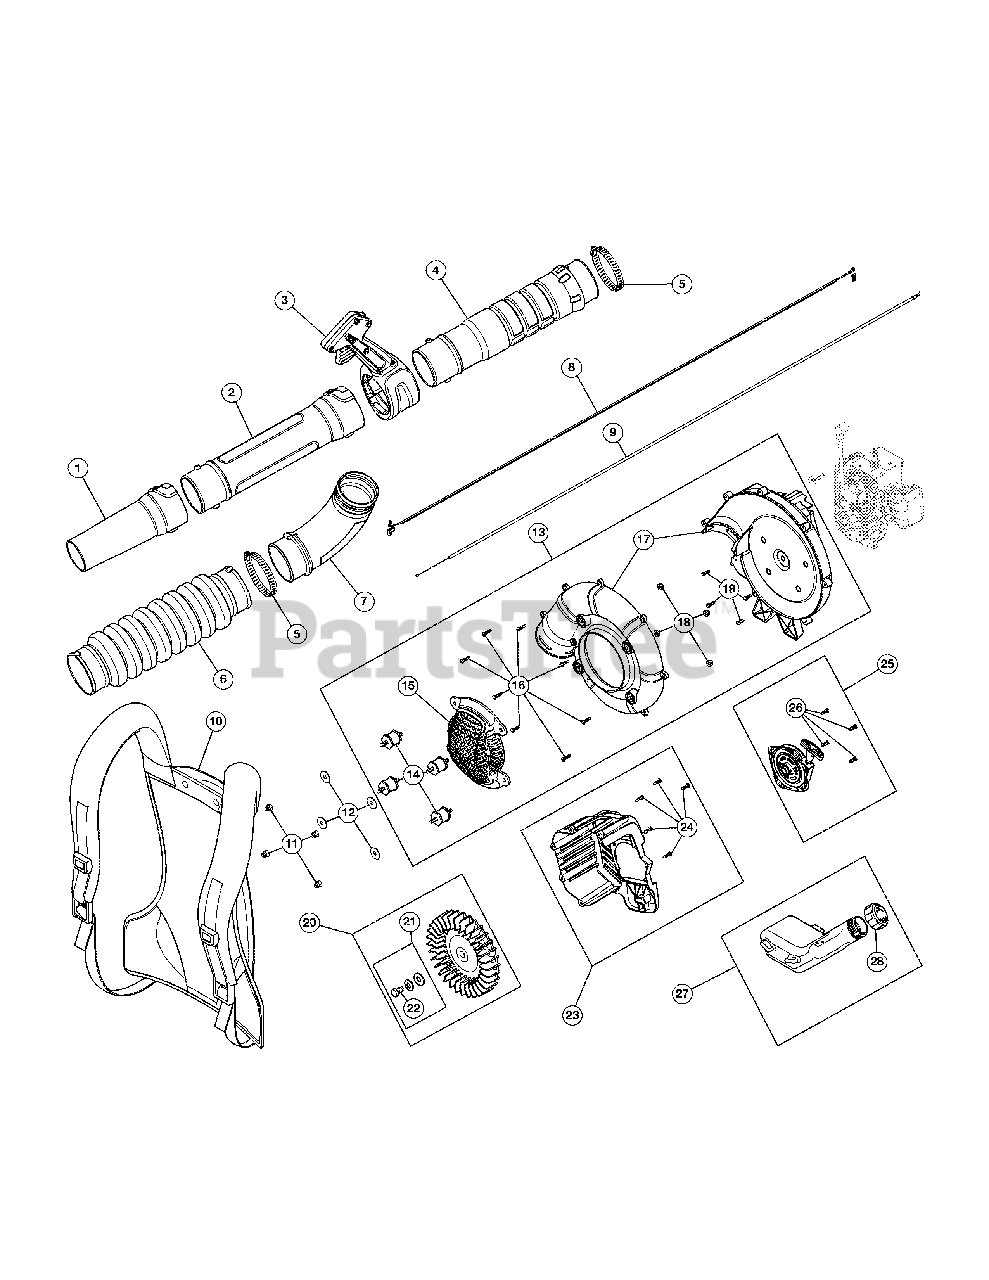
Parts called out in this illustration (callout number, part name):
1	Nozzle
2	Lower Blower Tube
3	Throttle Grip Assembly
4	Upper Blower Tube
6	Flex Tube
8	Lead Wire
9	Throttle Cable
10	Harness
11	Nut
12	Washer
13	Impeller Housing Assembly (Incl. 14 - 19)
14	Insulator Mount
15	Intake Cover
17	Impeller Housing
19	Screw
20	Impeller (Incl. 21 and 22)
21	Impeller Hardware (Incl. 22)
23	Housing Assembly (Incl. 24)
25	Starter Assembly (Incl. 26)
26	Screw
27	Fuel Tank Assembly (Incl. 28)
28	Fuel Cap
